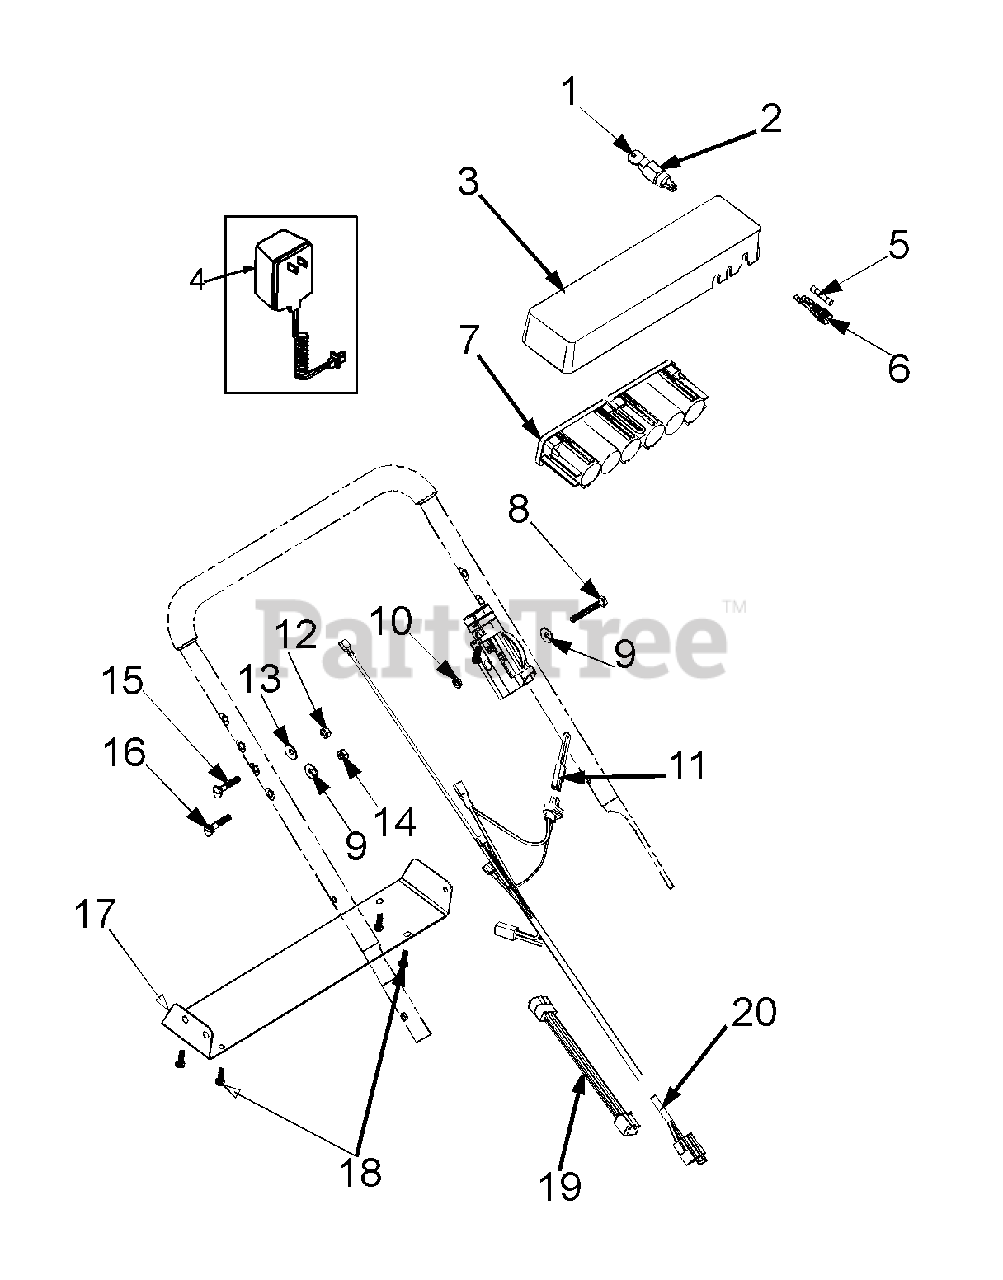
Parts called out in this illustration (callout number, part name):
1	Ignition Key
2	Key Switch
3	Battery Tray
4	Battery Charger
5	Fuse 7.5 Amp
6	Fuse Holder
7	Battery 12V
8	Hex Screw:1/4-20:2.0
9	Bell Washer .265 x .75 x .062
10	Special Hex Nut 5/16-18
11	Plug
12	Nut 5/16-18
13	Bell Wash .340 ID x .872 OD
14	Hex Nut 1/4-20
15	Carriage Bolt 5/16-18 x 1
16	Carriage Screw
19	Harness Extension
20	Harness
